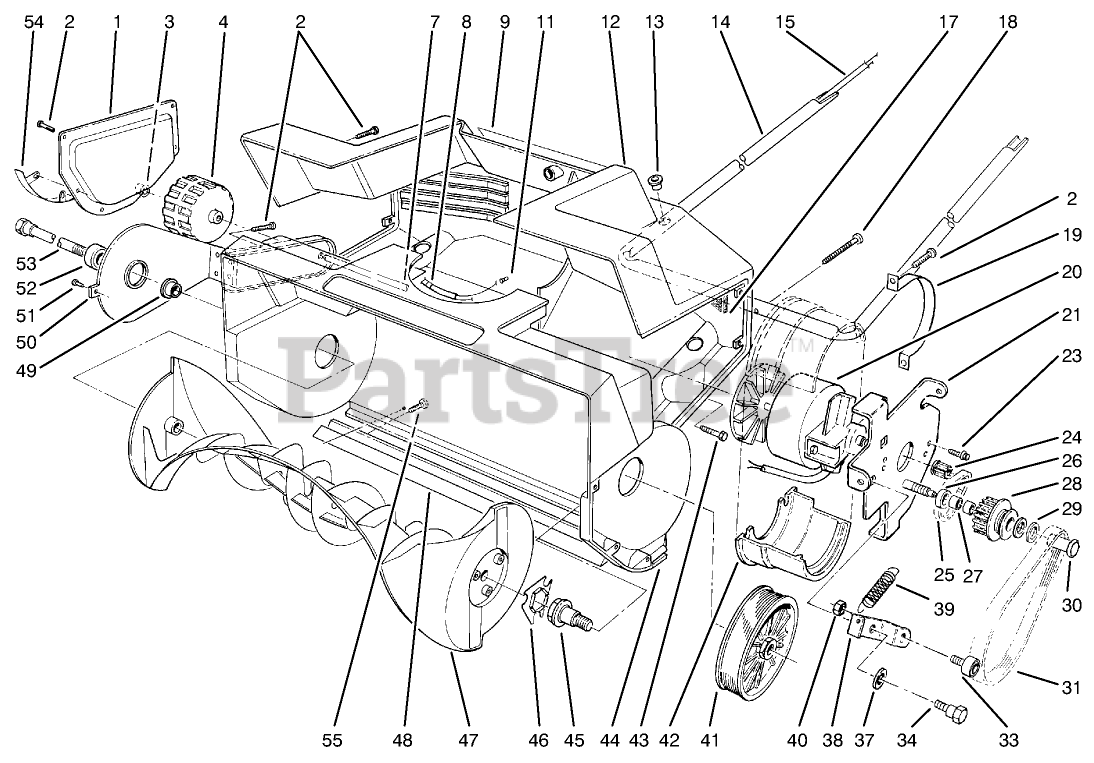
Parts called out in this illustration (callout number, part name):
2	SCREW-PPH
3	PUSHNUT-CAP, WASHER
4	WHEEL, 1200/1800
7	AXLE SHAFT
8	STRAIN RELIEF-GRIPMASTR
11	CONNECTOR SCREW
12	SHROUD - 1800 P.C.
13	BUSHING
17	FOAM FILTER
18	SCREW-PLASTIC, PPH
19	STRAP-MOTOR, FINISHED
20	MOTOR, 1800
21	PLATE - MOTOR ASSY.
23	TEKS SCREW
24	DRIVER PULLEY
25	BELT-PULLEY, IDLER/DRIVER
26	WASHER
27	Bearing-Needle
29	WASHER-THRUST
30	IDLER BOLT
33	IDLER BEARING
34	SCREW-SHOULDER
37	WASHER
38	IDLER BRACKET
39	IDLER SPRING
40	NUT-LOCK, NI
41	DRIVEN PULLEY
42	1800 CLAMP MTR BRCKT
43	SCREW-HWH THD CUT
44	ROTOR/HOUSING 1800
45	SHAFT, ROTOR DRIVE
46	COUPLER, ROTOR
47	ROTOR - 1800 SNOWBLOWER
48	SCRAPER - 1800
49	BUSHING
50	Bracket-Wheel (Incl. Ref. #52)
51	RIVET-POP
54	SKID, 1800
